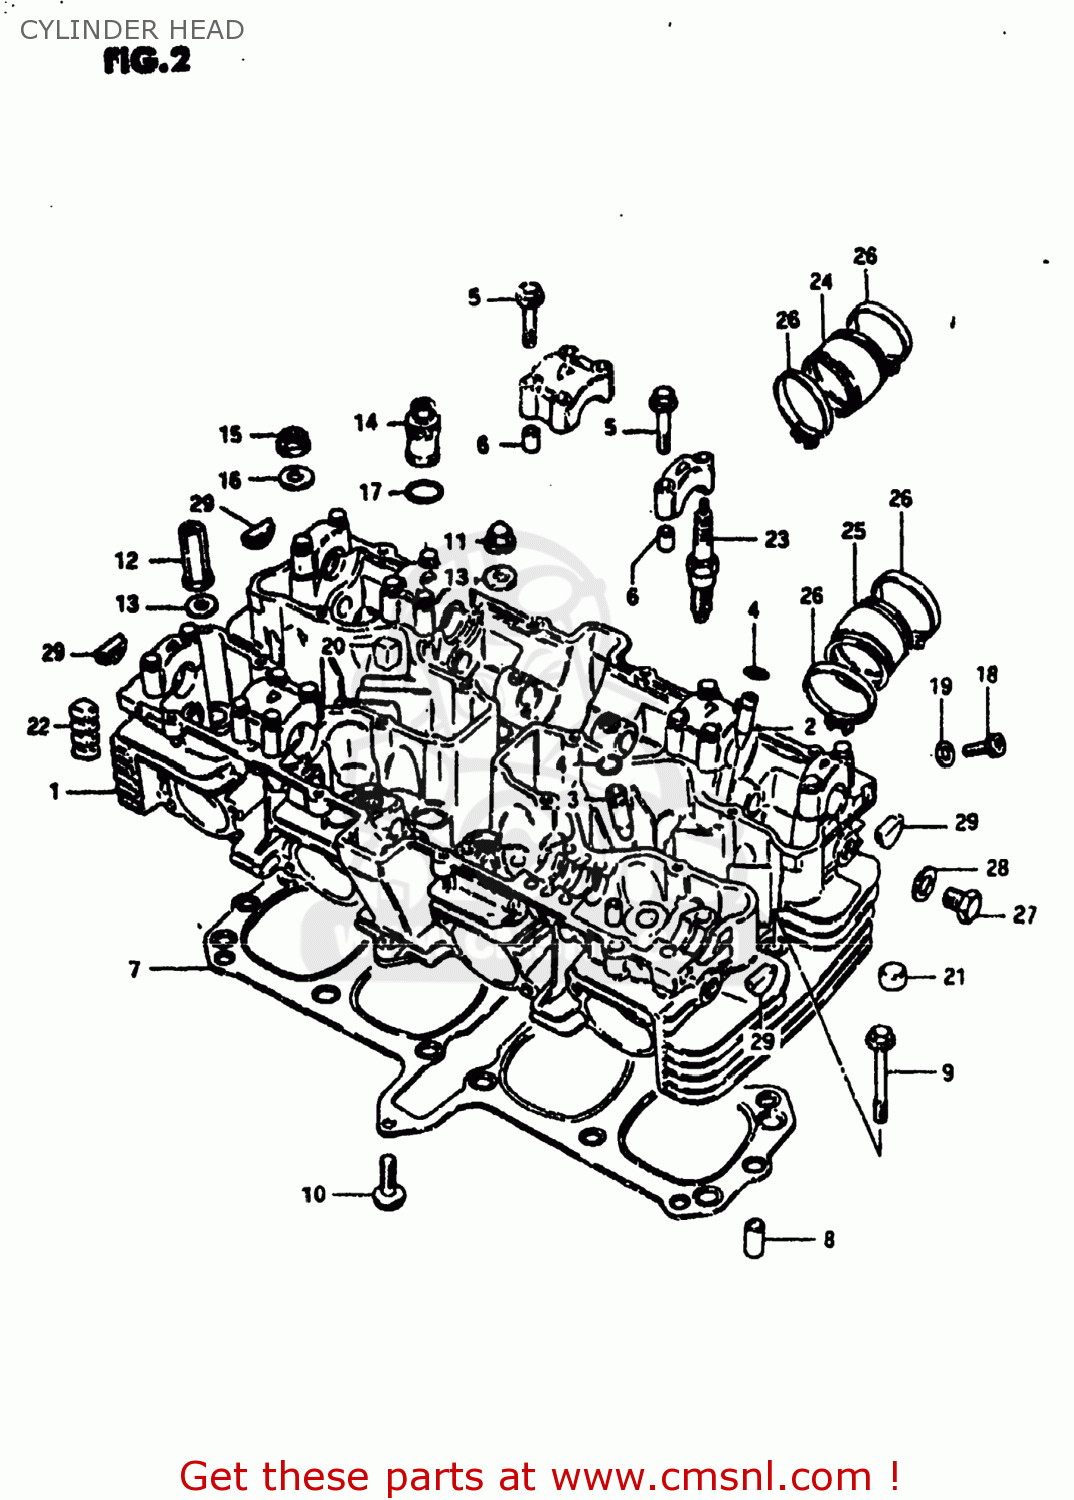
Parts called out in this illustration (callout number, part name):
1	HEAD ASSEMBLY,CYLINDER
2	GUIDE,INTAKE VALVE
3	GUIDE,INTAKE VALVE
4	RING,SNAP
5	BOLT(6X39)
6	PIN(6.2X8X11)
7	GASKET,CYLINDER HEAD (MCA)
8	PIN
9	BOLT
10	BOLT
11	NUT
12	NUT
13	GASKET(10.5X22X2) (NAS)
14	NUT,CYLINDER HEAD SEAL
15	NUT
16	WASHER(10.5X22X2.3)
17	O RING(D:2.4,ID:16.8)
18	BOLT
19	GASKET(5.3X9.3X1.2) (NAS)
20	PAD
21	PAD,CYLINDER HEAD
22	PAD,CYLINDER
23	SPARK PLUG D8EA
24	PIPE,INTAKE,R
25	PIPE,INTAKE
26	CLAMP
27	PLUG (14X12)
28	GASKET(14X19.2X2) (NAS)
29	PLUG
